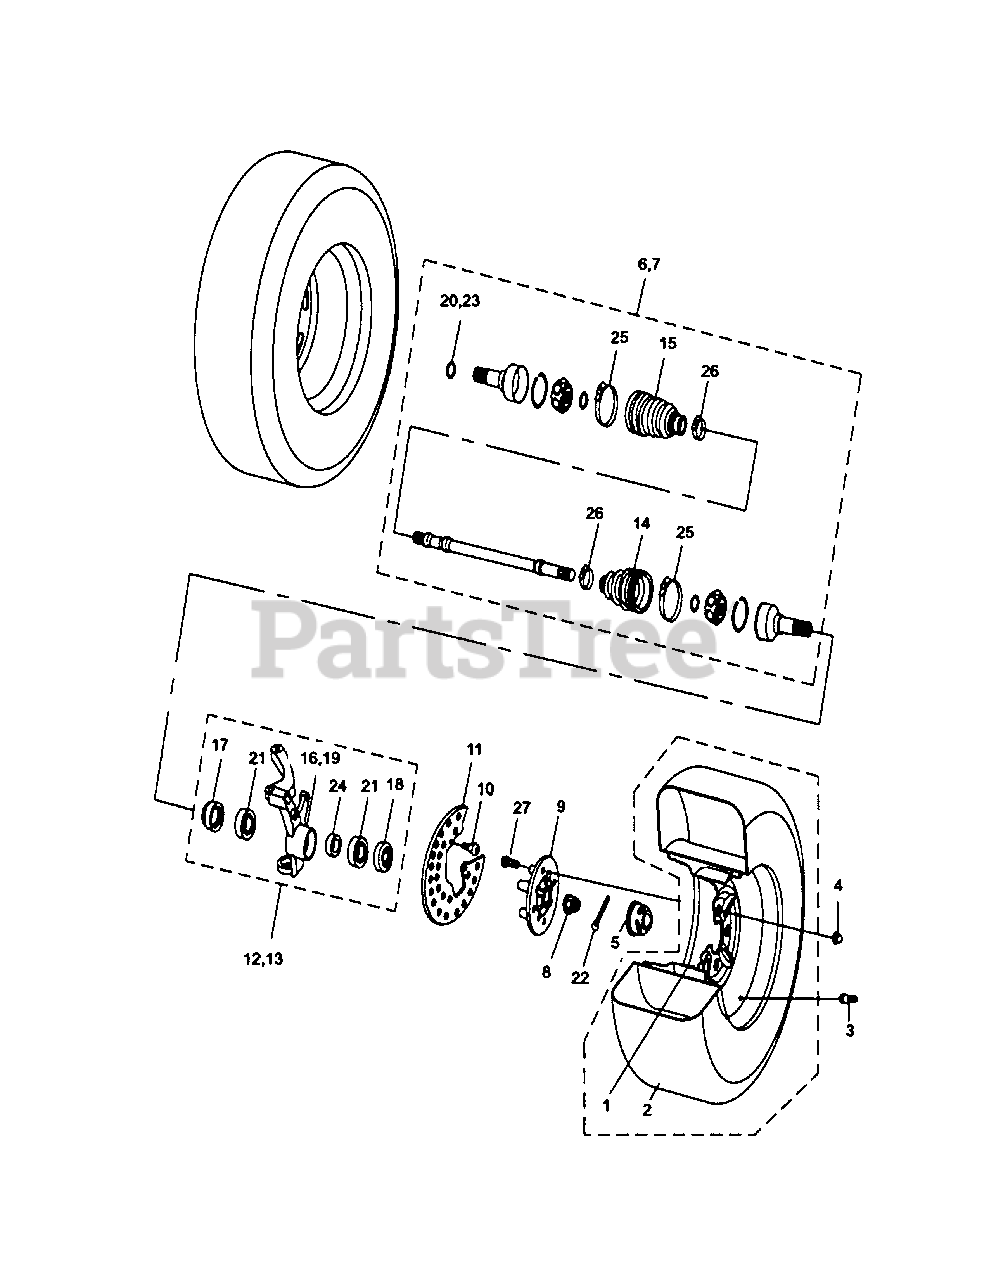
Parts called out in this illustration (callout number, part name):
1	Front Alu. Wheel F116
3	Cycle Valve
4	Nut M10
5	Wheel Caps II
6	Front Left C.V Axle
7	Front Right C.V Axle
10	Cross Large Plate Head Screw M6×12
11	Front Brake Disk Cover
12	Front Left Steering Knuckle Assy.
13	Front Right Steering Knuckle Assy.
14	Inner Rubber Dust-P Cover (C-1605)
15	Outer Rubber Dust-P Cover (C-1610)
16	Front Left Steering Knuckle
17	Inner Oil Seal, Front Knuckle 38×55×8
18	Outer Oil Seal, Front Knuckle 38×55×7
19	Front Right Steering Knuckle
21	Bearing DAC30×60×30
22	Cotter Pin 3.2×50
24	Inner Bushing
25	CV Boot Proof Clamp A
26	CV Boot Proof Clamp B
